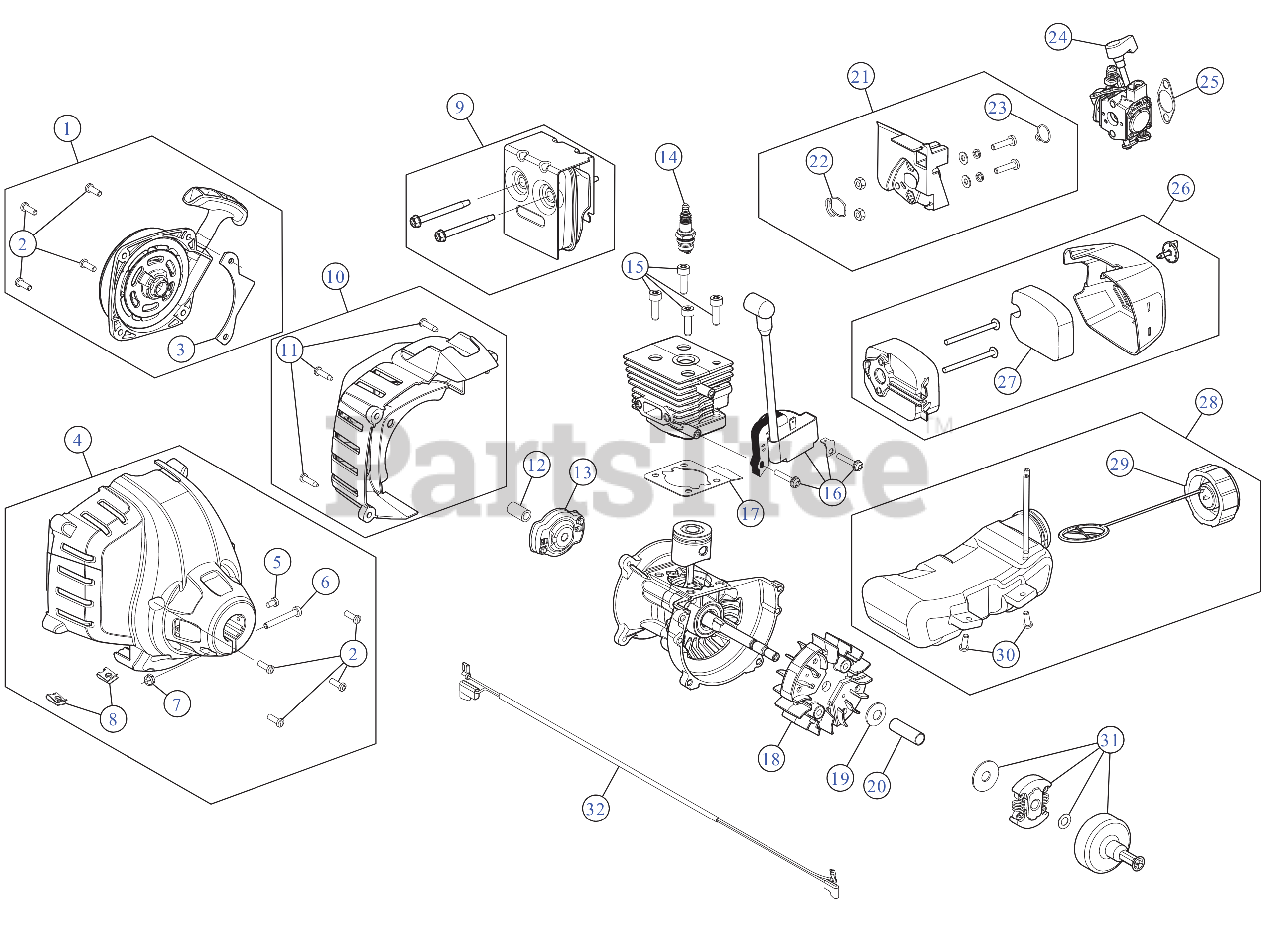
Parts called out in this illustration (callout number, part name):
1	STARTER ASSEMBLY RR
2	SCREW:10-32X.562:#8P
3	STARTER GUARD
4	CLUTCH COVER ASSEMBLY
5	SCREW, 8-32 x .312 P
6	SCREW
8	NUT, TINNERMAN U-T
9	MUFFLER ASSEMBLY
10	REAR ENGINE COVER
11	SCREW, #8-16X.750 PH
12	ELECTRIC START ADP
13	PAWL ASSEMBLY AC5
14	SPARK PLUG
15	SCREW 1/4 x 20 x .8125
17	GASKET CYL
18	FLYWHEEL ASSEMBLY 27CC
19	BELL WASHER
21	INTAKE ASSEMBLY
24	CARBURETOR (WALBRO)
25	GASKET CARB
26	AIRCLEANER ASSEMBLY
27	AIR FILTER
28	FUEL TANK ASSEMBLY
30	SCREW:10-6 x .75
31	SMALL CLUTCH ASSEMBLY W/SMALL DRUM
32	LEAD WIRES
